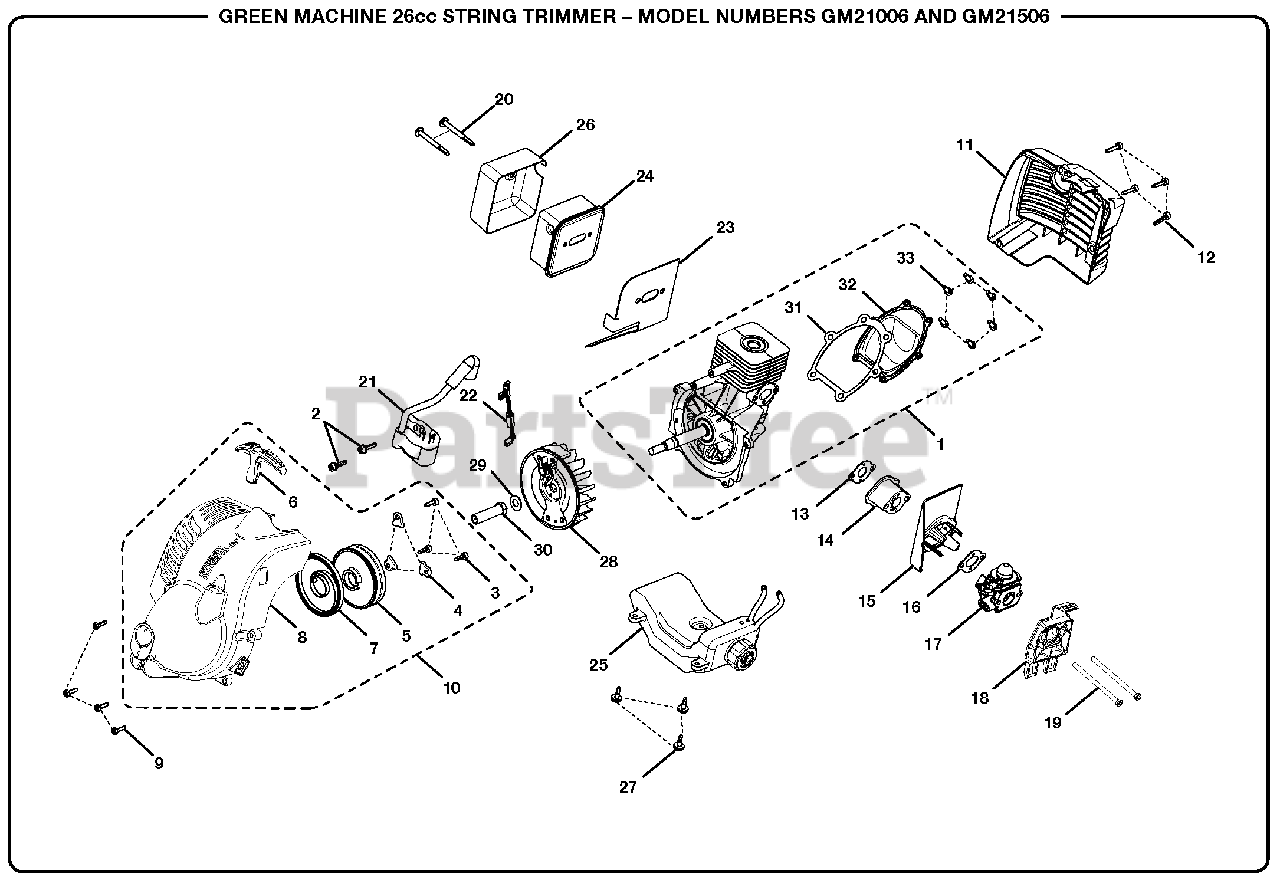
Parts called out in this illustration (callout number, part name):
1	Short Block Assembly
2	Screw (M4 x 19 mm)
3	Screw (M4 x 14 mm)
4	Pulley Retainer
5	Starter Pulley Assembly
6	Pulley Handle
7	Spring & Container Assembly
8	Front Housing
9	Screw (M4 x 16 mm)
10	Front Housing Assembly
11	Rear Housing
12	Screw (M4 x 8 mm)
13	Intake Gasket
15	Heat Dam Deflector
16	Carburetor Gasket
17	Carburetor
18	Choke Base
19	Screw (M5 x 70 mm)
20	Screw (10-24 x 2-3/16 in)
21	Ignition Module
22	Lead Assembly
23	Muffler Gasket
24	Muffler Assembly
25	Fuel Tank Assembly w/Cap
26	Heat Shield
27	Screw (M4 x 10 mm Shoulder)
28	Flywheel Assembly
29	Washer
30	Drive Connector
31	Gasket
32	Crankcase Cover
33	Screw (M4 x 12 mm)
